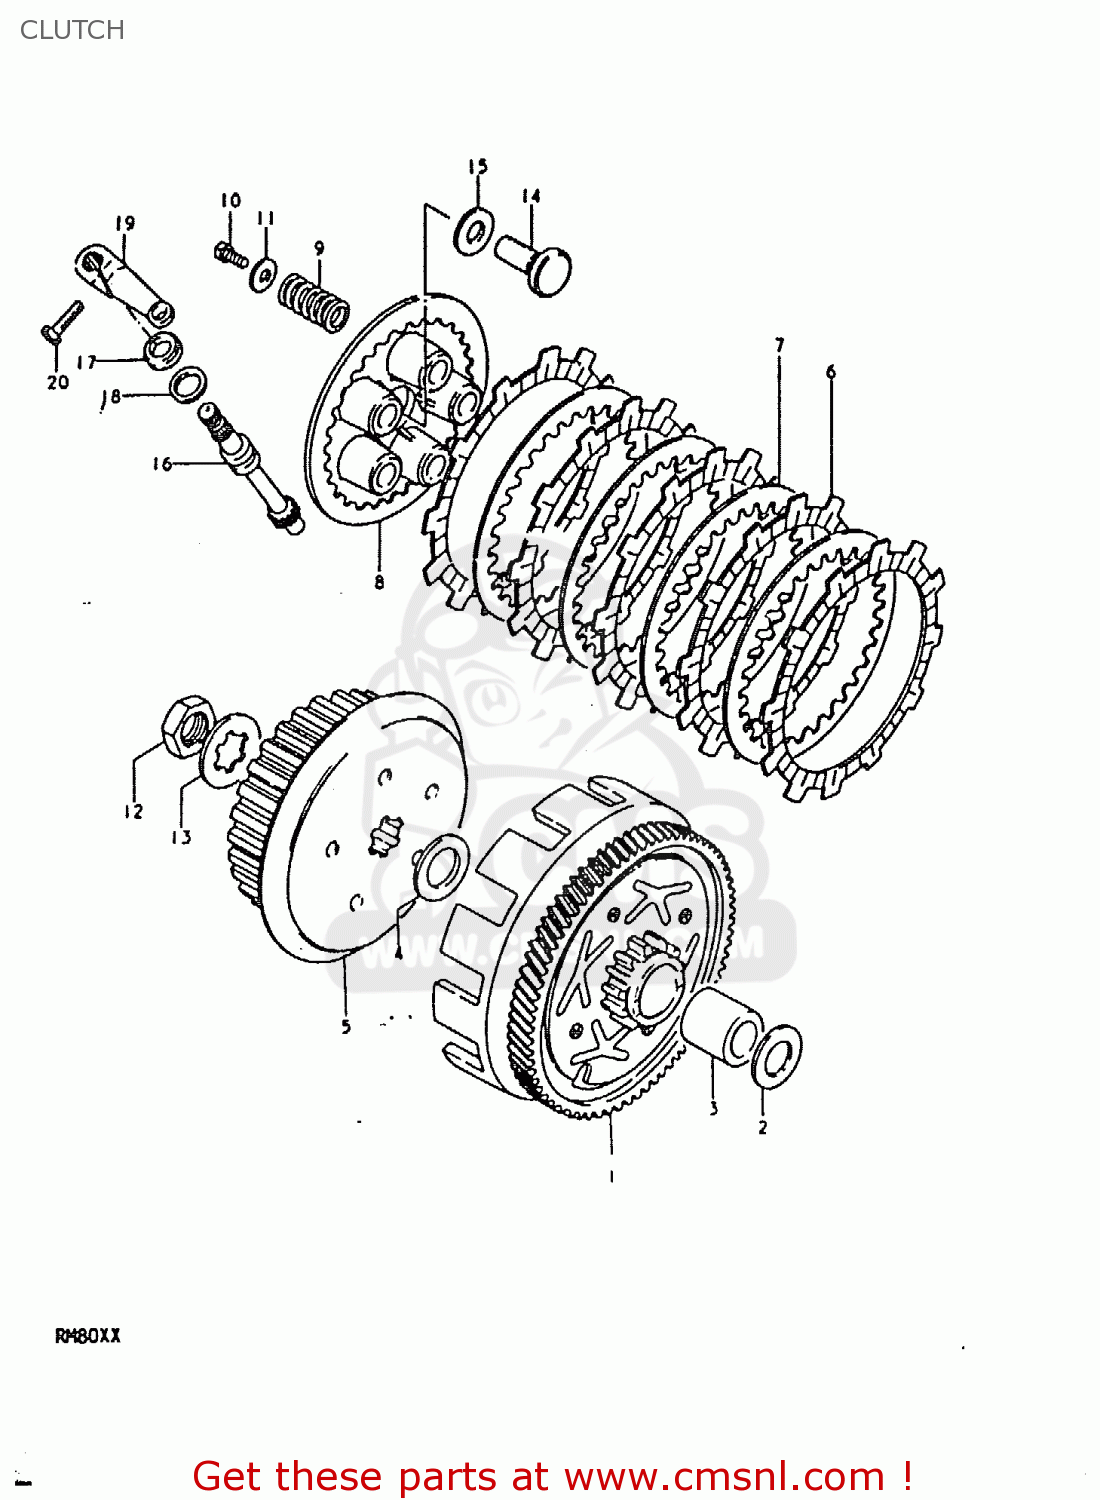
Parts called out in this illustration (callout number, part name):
1	GEAR ASSEMBLY,PRIMARY DRIVE
2	WASHER,THRUST
3	SPACER(17X22X28.5)
4	WASHER
5	HUB,CLUTCH SLEEVE
6	PLATE,CLUTCH DRIVE
7	PLATE,CLUTCH DRIVEN (NAS)
8	DISC,CLUTCH PRESSURE
9	SPRING
10	BOLT(5X16)
11	WASHER (5.5X16X1.2)
12	NUT
13	WASHER,LOCK
14	RACK,CLUTCH RELEASE
15	BEARING(10X22X2.8)
16	PINION,CLUTCH RELEASE
17	OIL SEAL
18	WASHER (12X17X1)
19	ARM,CLUTCH RELEASE
20	BOLT, UPPER
